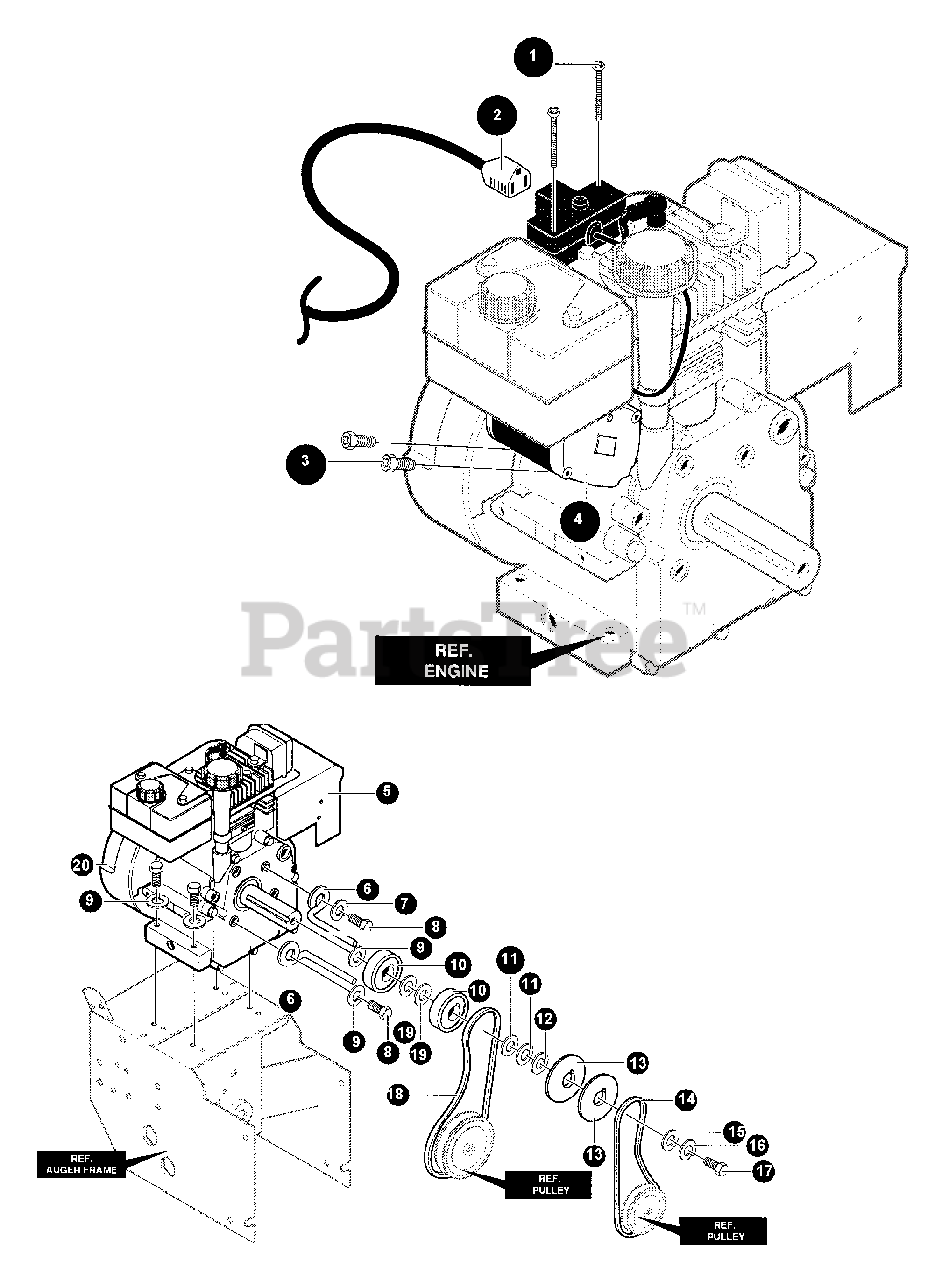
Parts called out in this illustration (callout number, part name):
1	SCREW - 6-32 X 2-1/2"
2	CORD, STARTER MOTOR
3	SCREW - 1/4-20 X .50"
4	MOTOR, STARTER TEC
5	ENGINE - 10 HP TEC
6	GUIDE, ROD BELT - RIGHT
7	LOCKWASHER
8	SCREW - 5/16-24 X 5/8"
9	LOCKWASHER
10	PULLEY, HALF
11	WASHER
12	SPACER
13	PULLEY, ENGINE
14	BELT, AUGER 4L 36.8
15	WASHER
16	LOCKWASHER
17	SCREW - 3/8-24 X 1.00" -- NYLON
18	BELT, V 3L 33.13LG
19	WASHER, FLAT .752X.91X.02
20	SCREW - 5/16-18
